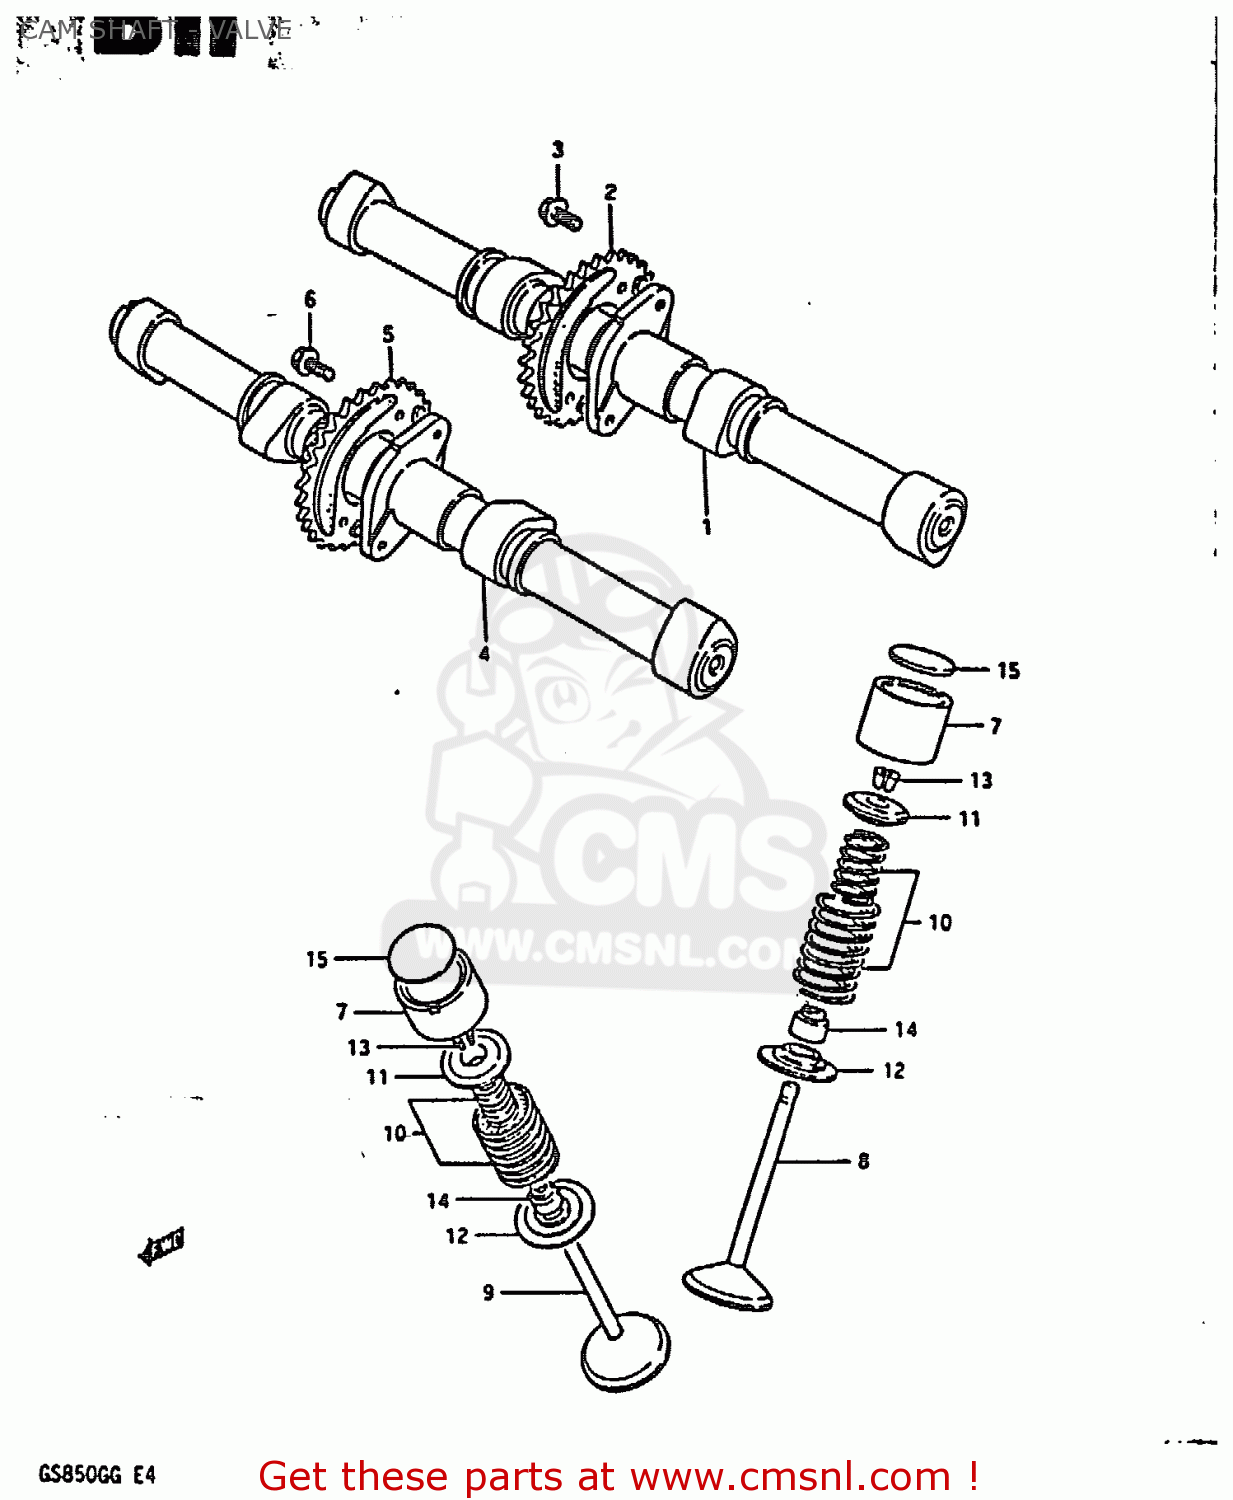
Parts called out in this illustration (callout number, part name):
1	CAMSHAFT,INTAKE
2	SPROCKET,INTAKE CAMSHAFT
3	BOLT(7X11)
4	CAMSHAFT,EXHAUST
5	SPROCKET,EXHAUST CAMSHAFT
6	BOLT(7X11)
7	TAPPET,INTAKE
8	VALVE,INTAKE
9	VALVE,EXHAUST
10	SPRING SET,VALVE
11	RETAINER,VALVE SPRING
12	SEAT,VALVE SPRING
13	COTTER VALVE
14	SEAL,OIL(7X14.4X9)
15	SHIM,TAPPET(T:2.15)
